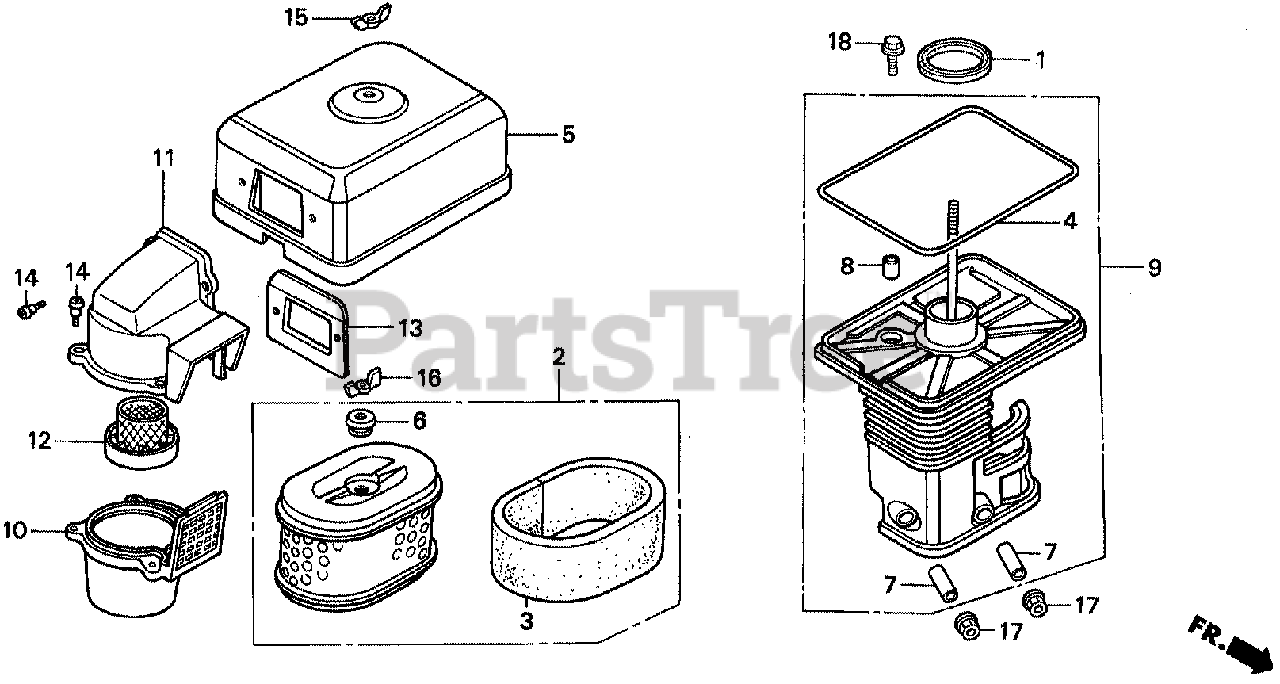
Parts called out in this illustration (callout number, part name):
1	GASKET, ELBOW
2	ELEMENT, AIR CLEANER (DUAL)
3	FILTER (OUTER)
4	GASKET, AIR CLEANER COVER
5	COVER, AIR CLEANER (DUAL)
6	GROMMET, AIR CLEANER
7	COLLAR, AIR CLEANER
8	COLLAR B, AIR CLEANER
9	ELBOW, AIR CLEANER
10	CASE, PRE AIR CLEANER
11	CAP, PRE AIR CLEANER
12	GUIDE, PRE AIR CLEANER
13	PLATE, PRE AIR CLEANER
14	BOLT, MUDGUARD
15	WINGNUT, TOOL BOX SETTING
16	WINGNUT, TOOL BOX SETTING
17	NUT, FLANGE (6MM)
18	BOLT, FLANGE (6X20)
